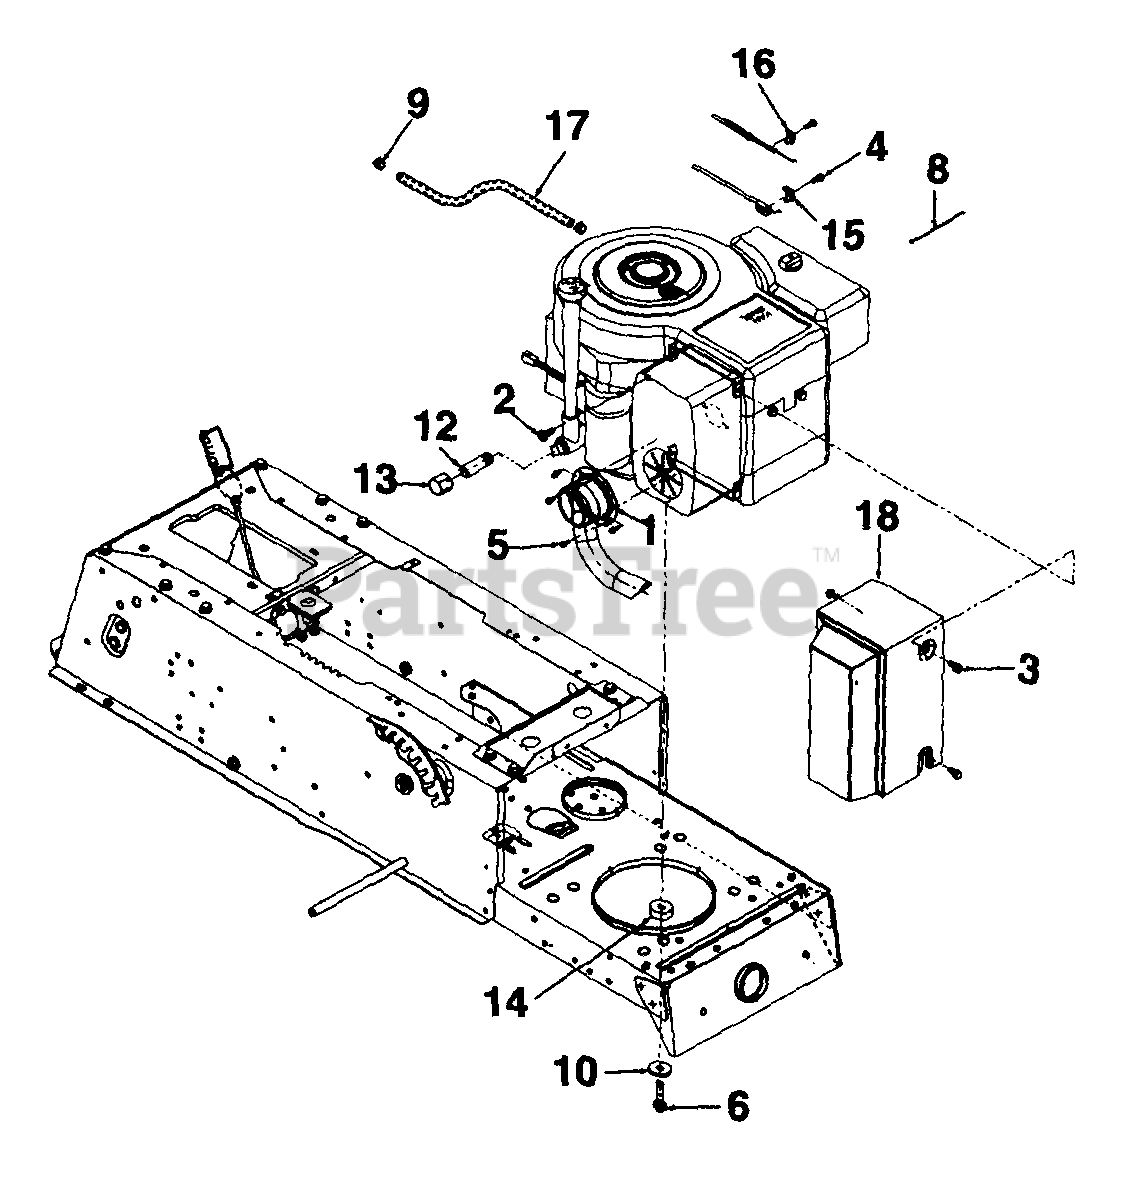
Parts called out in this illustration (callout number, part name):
1	Exhaust Pipe Ass'y.
2	Pan Hd. Mach. Scr. 5/16-18 x .75" Lg.
3	Hex Wash. Hd. Scr. 1/4 x 20 x .5" Lg.
4	Hex Wash. Hd. Scr. #10-32 x 5/8" Lg.
5	Hex Wash. Tap Scr. #8-32 x .38" Lg.
6	Hex L-Wash. TT-Tap Scr. 3/8-16 x 1.5" Lg.
10	Fl-Wash. 3/8" I.D. x 1.25" O.D.
12	Pipe Nipple 3/8-18 NPT
13	Oil Drain Cap
14	Shld. Spacer .38" I.D. x 1.25"
15	Casing Clamp
17	Fuel Line
18	Muffler Heat Shield Ass'y.
